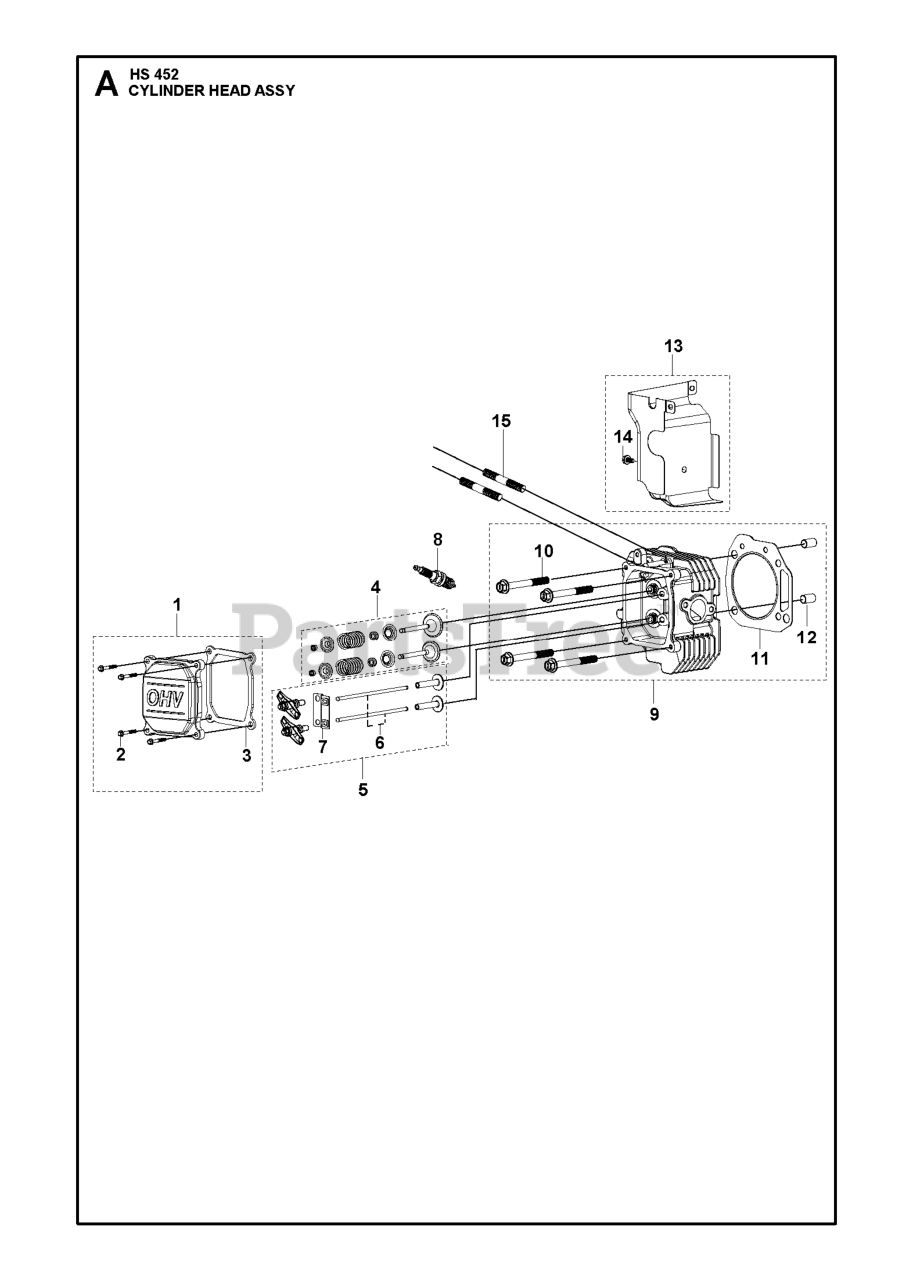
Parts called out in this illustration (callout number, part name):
1	CYLINDER HEAD KIT
2	BOLT GB/T 5789: M6 L=25
3	GASKET CYLINDER HEAD COVER GAS
4	SERVICE KIT KIT.VALVE (KIT 10)
5	SERVICE KIT KIT.ROCKER.ARM. (K
6	PUSH ROD PUSH ROD SET
7	PLATE PUSH ROD GUIDE PLATE
8	SPARK PLUG HQT-9 RESISTOR
9	CYLINDER HEAD KIT CYLINDER HEA
10	Husqvarna TBD
11	GASKET CYLINDER HEAD GASKET
12	PIN LOCATION PIN
13	DEFLECTOR AIR DEFLECTOR KIT
14	BOLT GB/T 5789: M6 L=12
15	STUD T381: 5/16-18/M8 L=34
